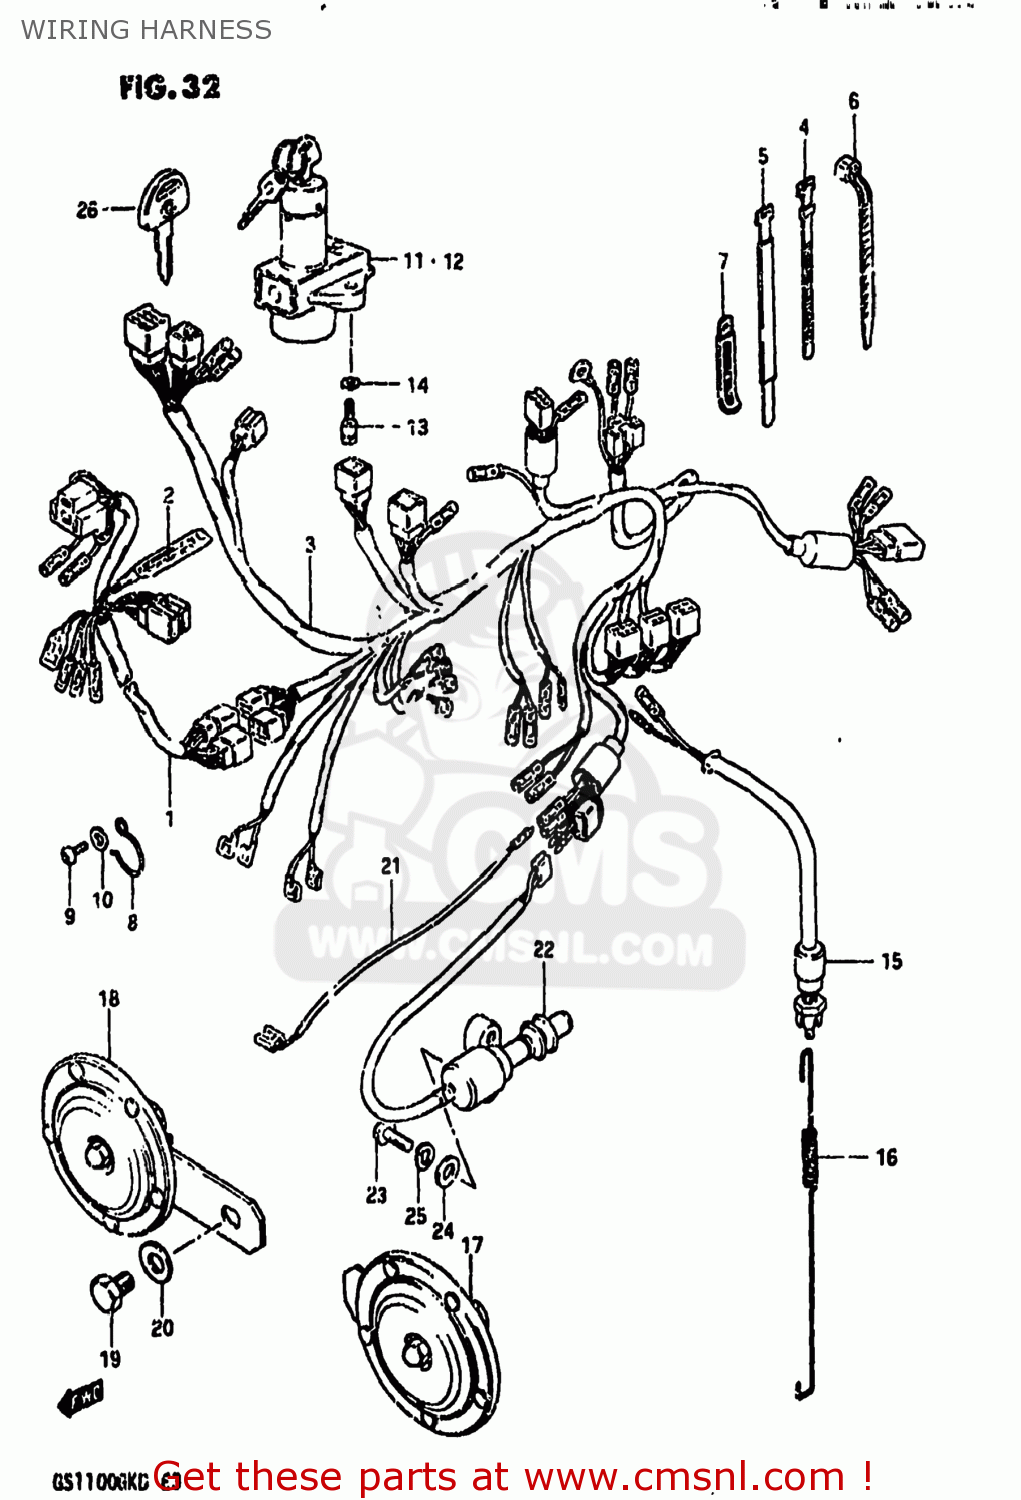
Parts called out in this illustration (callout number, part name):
1	HARNESS,WIRING NO.1
2	DIODE
3	HARNESS,WIRING NO.2
4	CLAMP(L:120)
5	CLAMP
6	CLAMP
7	CLAMP
8	GUIDE,WIRING HARNESS
9	SCREW 6X12
10	WASHER
11	LOCK ASSEMBLY,STEERING
12	SWITCH ASSEMBLY,IGNITION
13	BOLT
14	LOCK WASHER
15	SWITCH ASSEMBLY,STOP LAMP
16	SPRING
17	HORN ASSEMBLY,LOW PITCH
18	HORN ASSEMBLY,HIGH PITCH
19	BOLT 8X12
20	WASHER
21	WIRE
22	SWITCH ASSEMBLY,SIDE STAND
23	BOLT
24	WASHER
25	LOCK WASHER
26	KEY,BLANK
